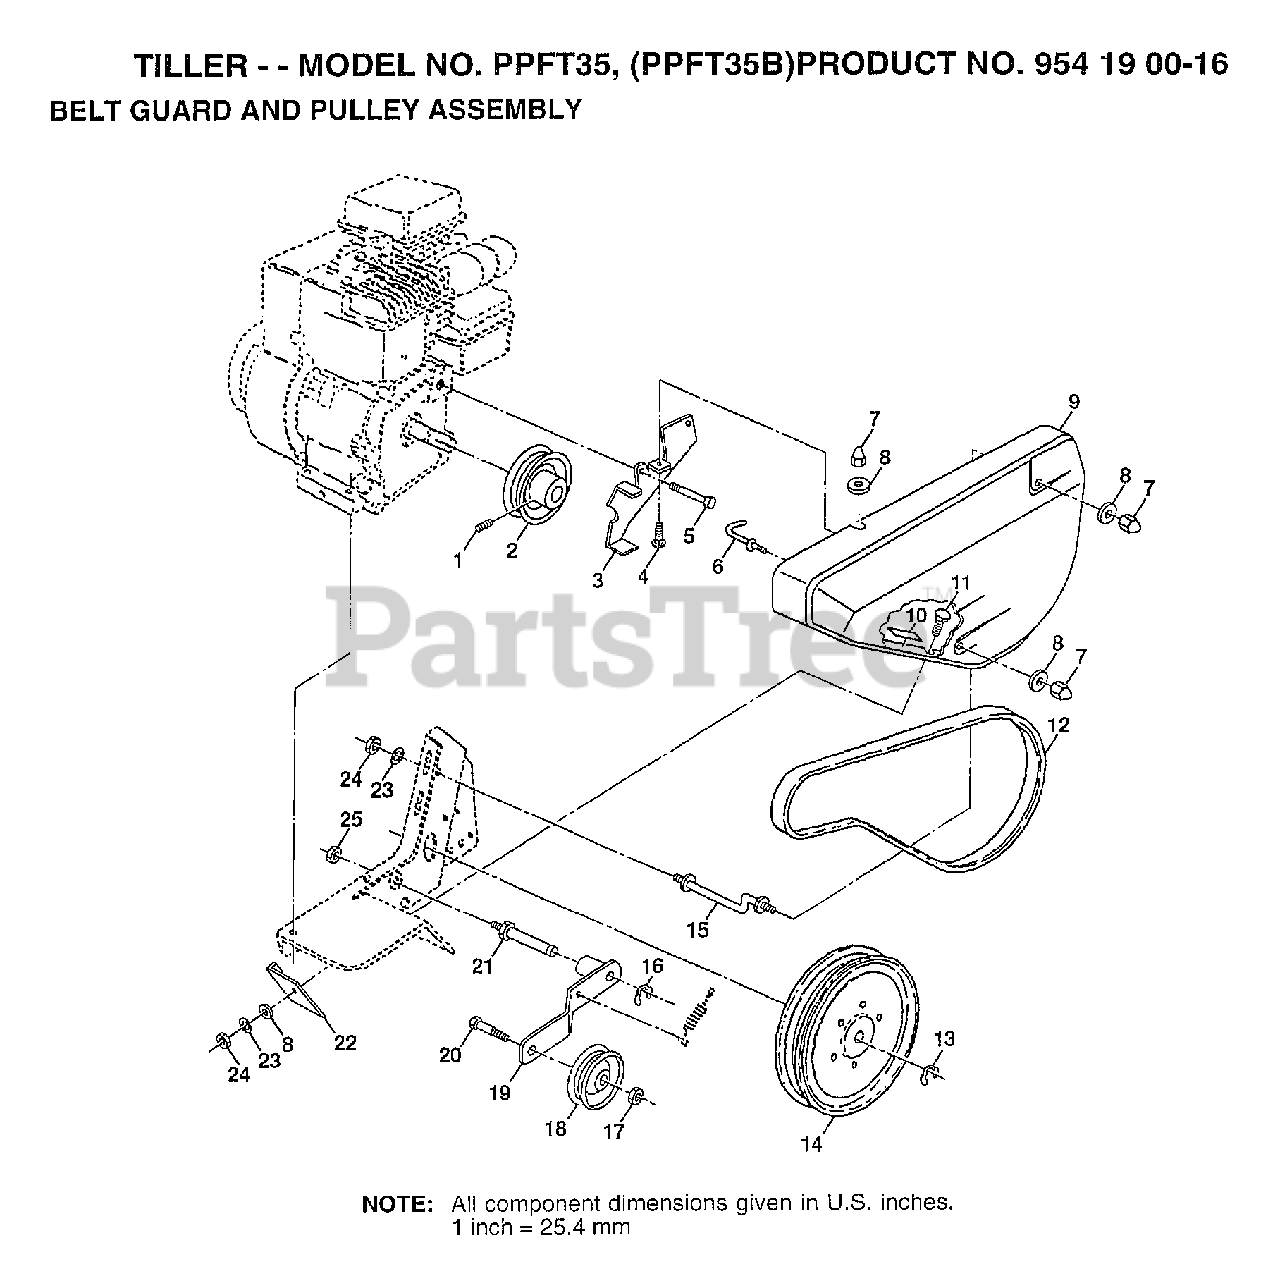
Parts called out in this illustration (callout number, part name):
1	SET SCREW
4	BOLT
5	BOLT.HEX.HEAD
7	NUT-CAP TI
8	WASHER
10	PAD IDLER TI
11	BOLT T
14	PULLEY.TRANSMISSN
16	KLIP RING TI
17	NUT
18	"PULLEY,IDLER"
19	"ARM, IDLER"
21	SHAFT IDLER TI
22	SHIELD-DIRT TI
23	LOCKWASHER
25	JAM NUT TI
